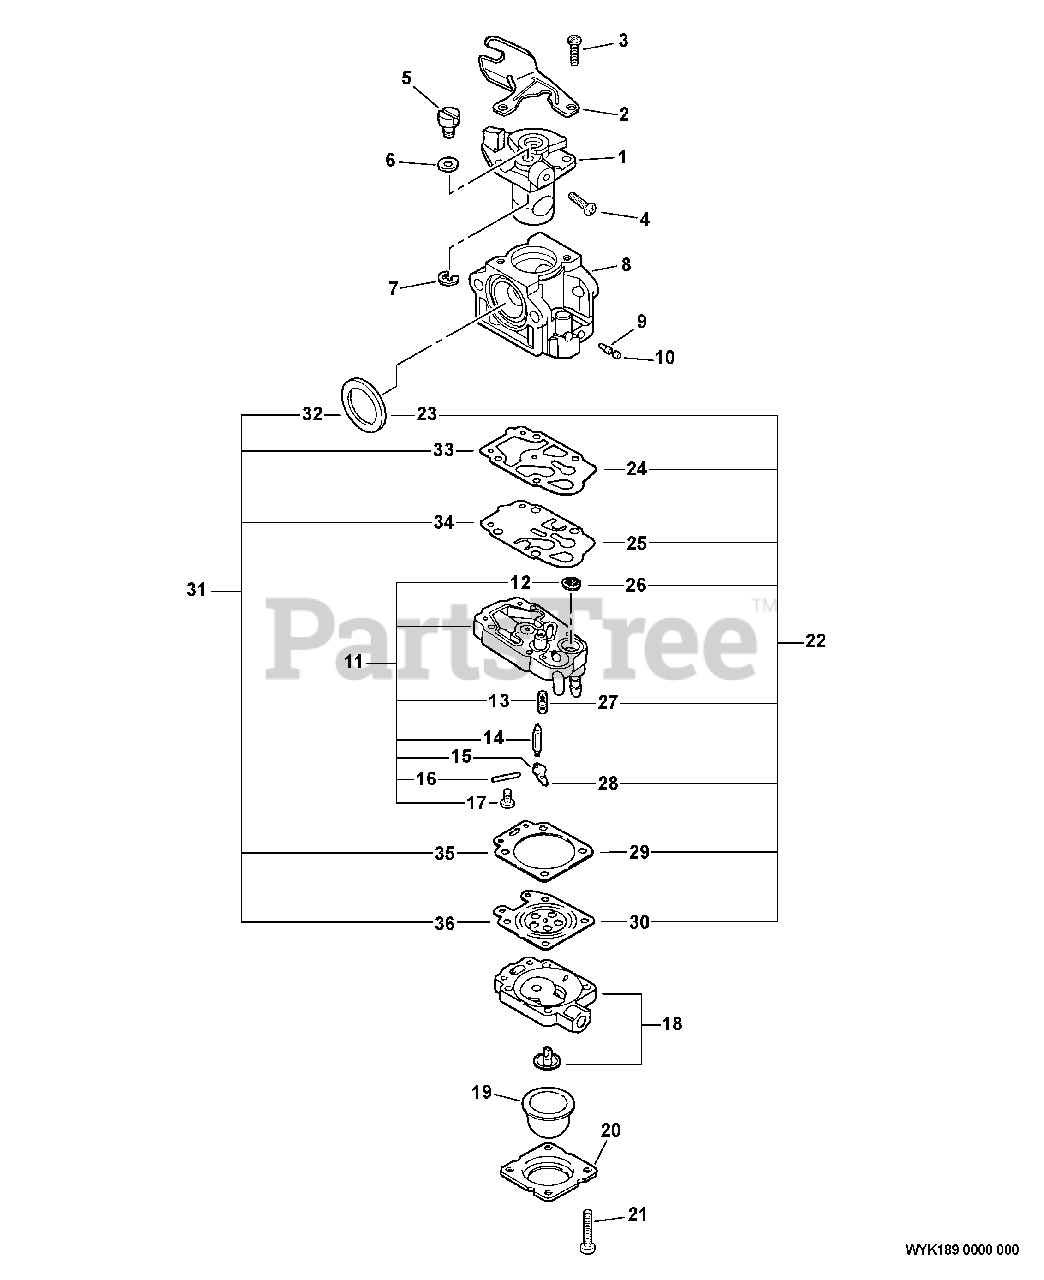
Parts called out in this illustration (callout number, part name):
1	THROTTLE VALVE ASSY
2	BRACKET, CABLE
4	SCREW, IDLE ADJUST
7	RING, RETAINING
8	BODY, CARBURETOR
9	NEEDLE - HIGH SPEED
10	CAP, LIMITER
11	BASE, PURGE
12	STRAINER
13	SPRING, METERING LEVER
14	VALVE, INLET NEEDLE
15	LEVER, METERING
16	PIN, METERING LEVER
17	SCREW, METERING LEVER PIN
18	PURGE BASE ASSY
19	BULB, PURGE
20	RETAINER, PURGE BULB
21	SCREW, PUMP COVER
22	REPAIR KIT
23	SEAL
24	GASKET, PUMP
25	DIAPHRAGM, PUMP
26	STRAINER
27	VALVE, INLET NEEDLE
28	LEVER, METERING
29	GASKET, DIAPHRAGM
30	DIAPHRAGM, METERING
31	DIAPHRAGM/GASKET KIT
32	SEAL
33	GASKET, PUMP
34	DIAPHRAGM, PUMP
35	GASKET, DIAPHRAGM
36	DIAPHRAGM, METERING
